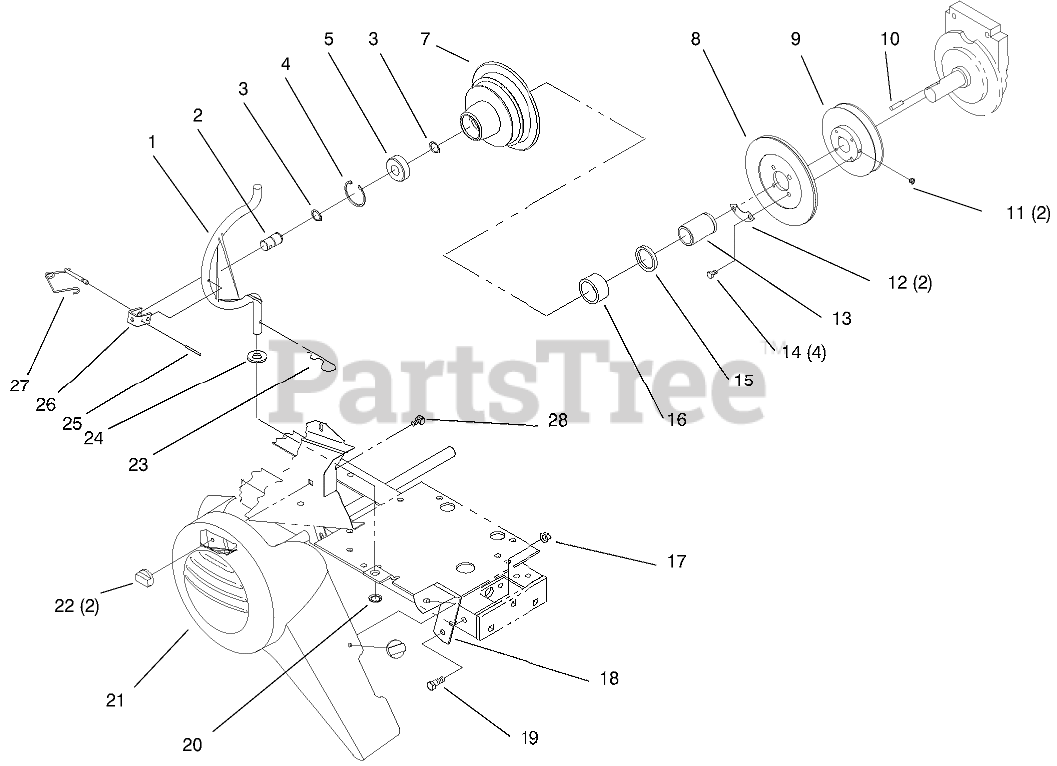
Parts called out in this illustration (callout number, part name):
1	ROD-HOUSING
2	SHAFT-PTO
3	Ring-Snap
4	RING-RETAINING
5	BEARING-BALL
7	Housing-Clutch
8	Facing-Clutch
8	ASS'Y-CLUTCH PLATE
9	PULLEY
11	SCREW-SET, HSH
12	RETAINER
13	RACE-BEARING
14	SCREW-HEX HD CAP
15	SEAL-OIL
16	Seal
17	NUT-FLANGE
18	Bracket
19	SCREW-HH
20	RING-REINFORCED CIRC
21	GUARD - BELT
22	NUT - WING
23	PIN-COTTER, HAIR
24	WASHER-FLAT
26	CLEVIS
27	LOCKING PIN ASM
28	Retainer-Bolt
